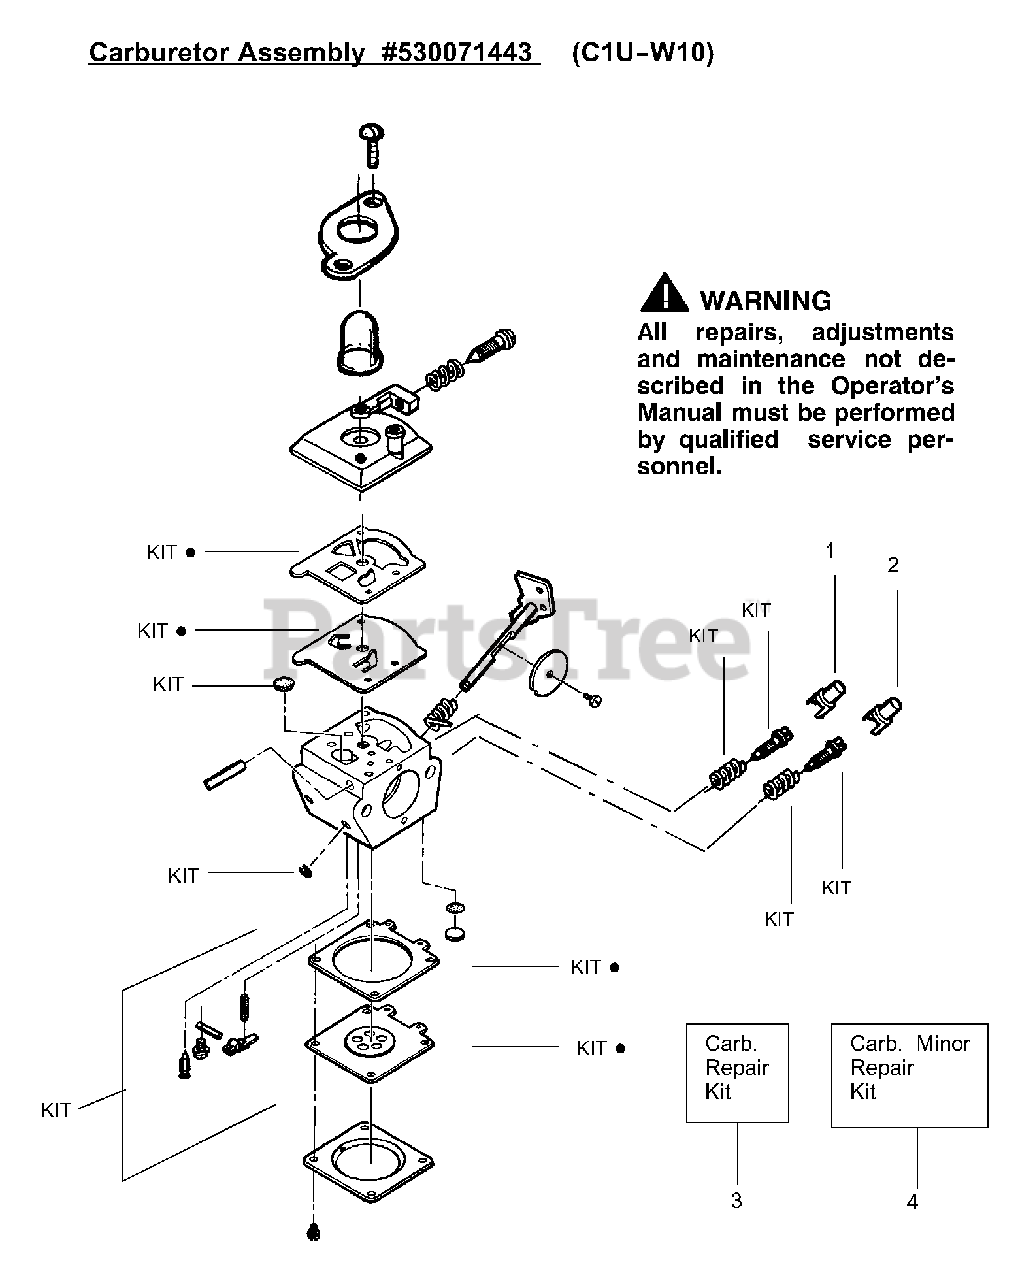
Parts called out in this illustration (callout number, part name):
1	Limiter Cap (low)
2	Limiter Cap (high)
3	Kit-Carburetor Repair
4	Kit-Carburetor Minor Repair
530071443	Carburetor Assembly (C1U-W10)
